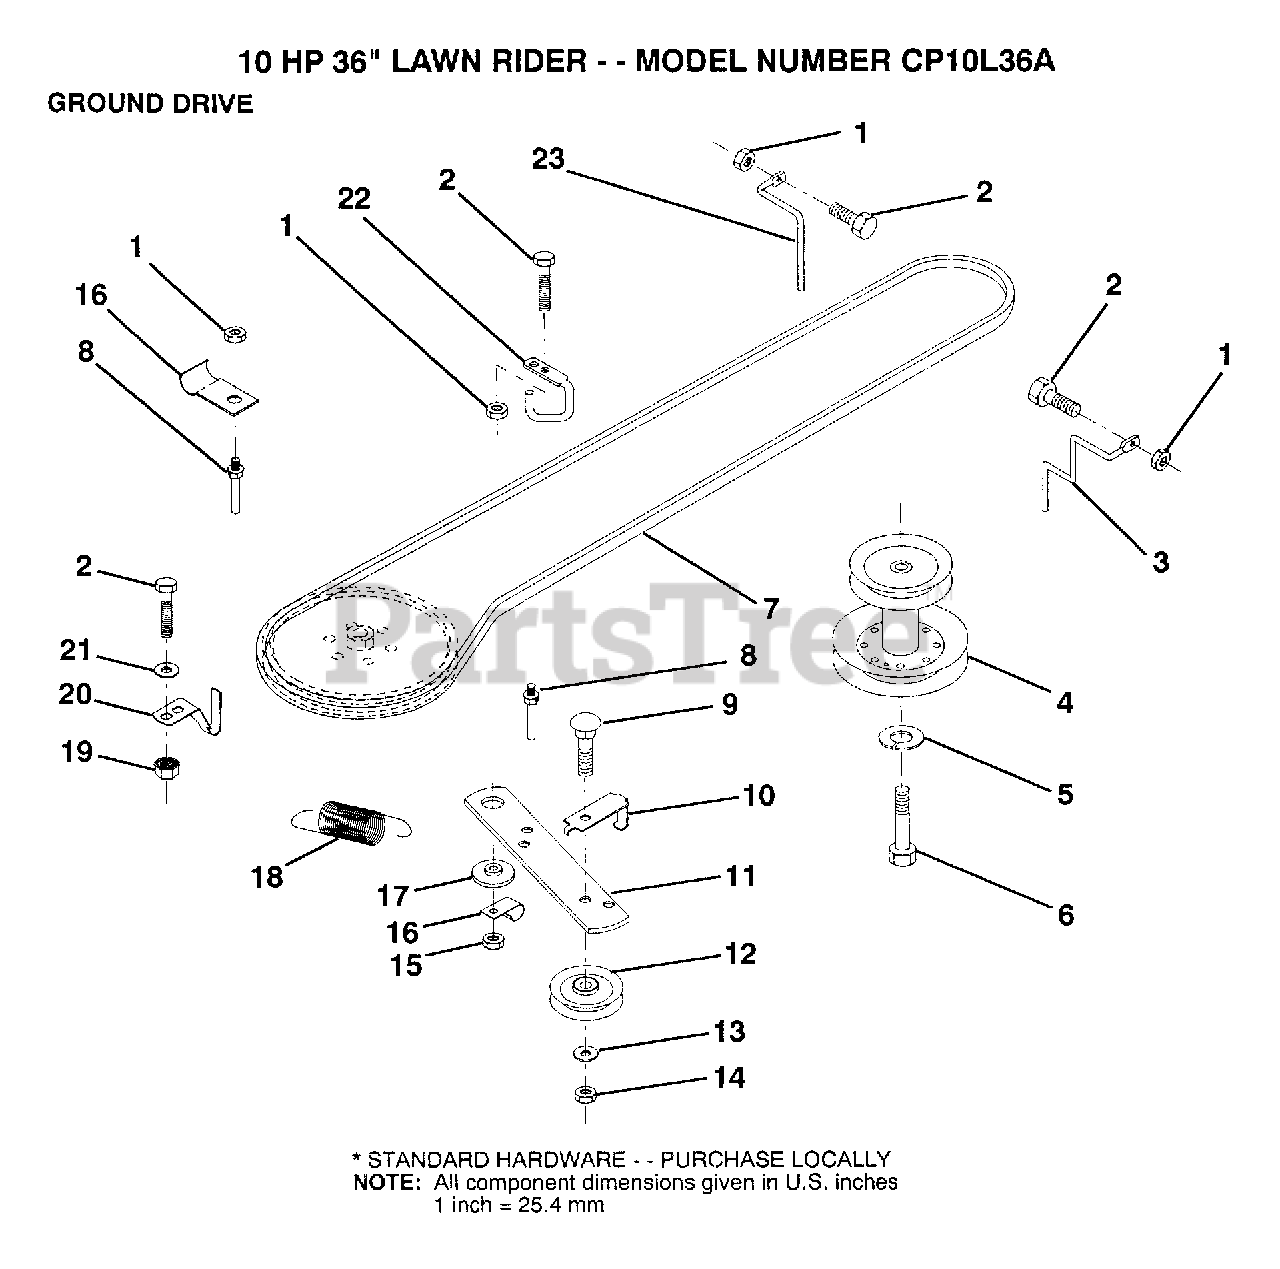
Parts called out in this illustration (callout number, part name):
2	BOLT
5	LOCKWASHER
6	HEX BOLT
7	BELT
8	"KEEPER,DRIVE BELT"
9	BOLT
10	"KEEP,IDLER DR BEL"
13	WASHER
14	LOCKNUT
16	"CLIP,INSULATOR"
17	SPACER RETAINER
20	"KEEPER,DR BELT "
21	WASHER
22	"KEEPER,FRA DR BEL"
